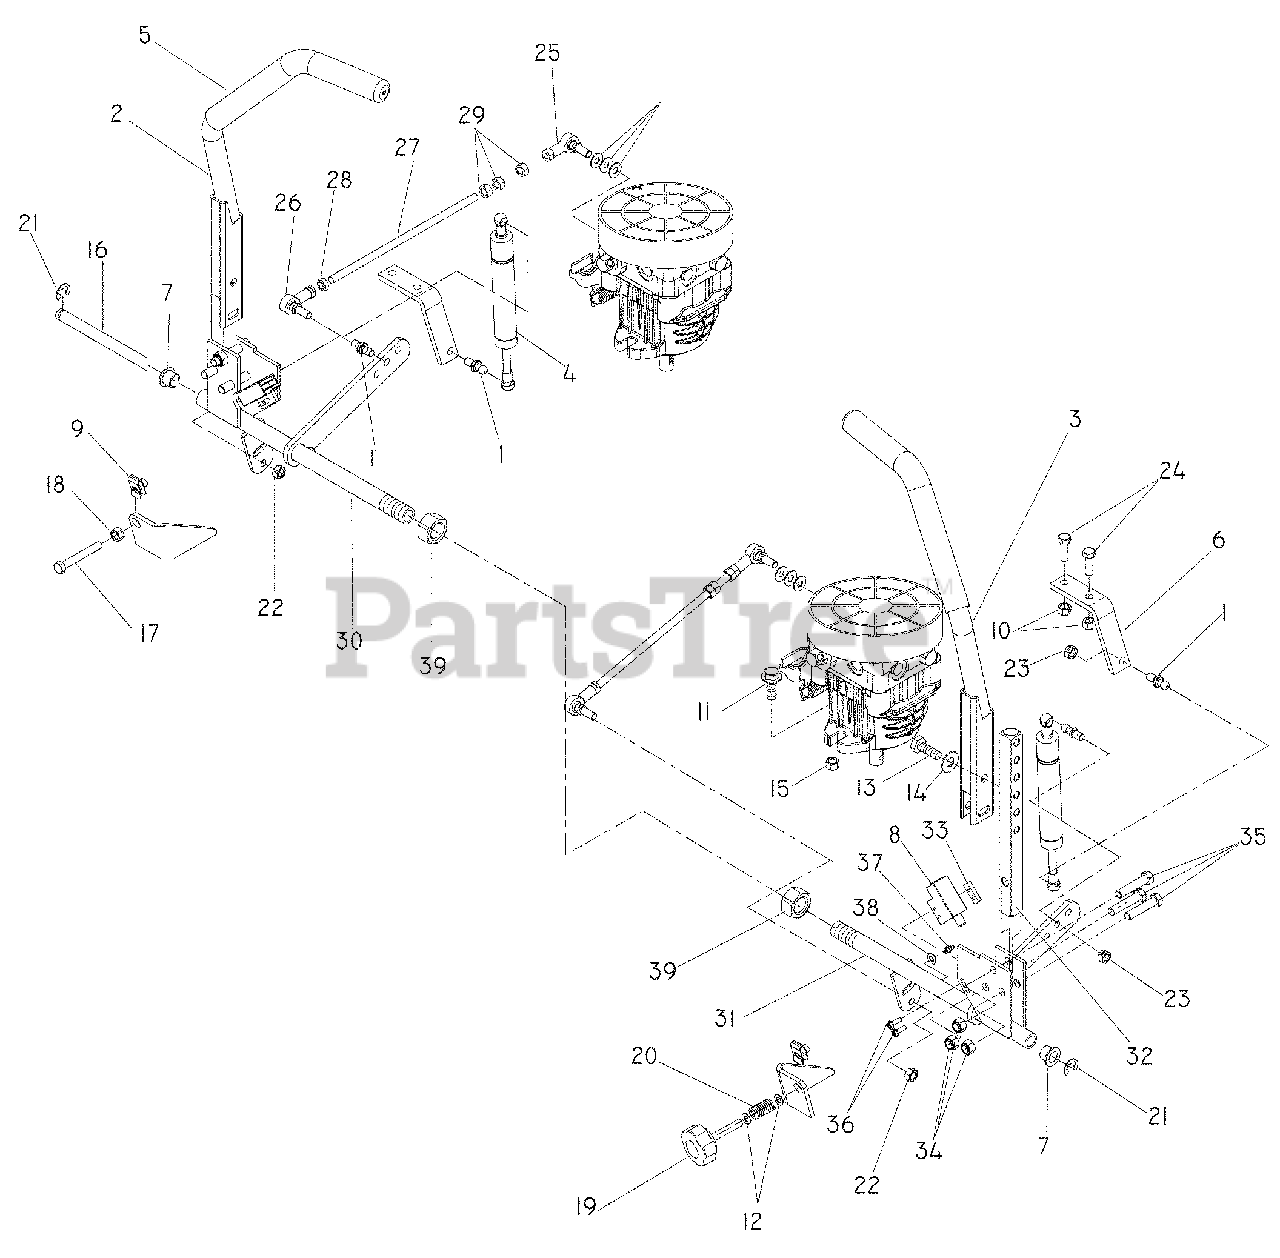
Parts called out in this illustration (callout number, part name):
2	DRIVE LEVER W/GRIP, RT
3	DRIVE LEVER W/GRIP, LT
4	DAMPENER
6	DAMPENER BRACKET
8	INTERLOCK SWITCH
9	"U" CLIP, 5/16C
10	NUT 5/16-18 HEX NYLOC
11	HCS 3/8-16 x 1 WHIZLK
12	WASHER, 5/16 STD FLT
13	HCS, 3/8 -16 x 1
14	SPRING WASHER, 3/8
15	NUT 3/8-16, CENTERLOCK
16	CONTROL SHAFT
17	HCS, 5/16C x 1¾, TAPBOLT
21	E-RING, ½"
22	NUT 5/16F, NYLOC
23	NUT 5/16-18 CENTERLOCK
24	HCS 5/16-18 x 1
25	ROD END, RT
26	ROD END, LT
27	TRACKING LINKAGE
28	NUT 5/16F, LH, JAM
30	CONTROL, RT
31	CONTROL, LT
32	ARM, CONTROL SHAFT
33	SCREW PLATE
34	NUT 3/8-16 HEX NYLOC
35	HCS, 3/8 -16 x 1¾
36	SCREW, 10-24 x 5/8
37	ZERK
39	NUT ¾-16 CNTRLOCK
